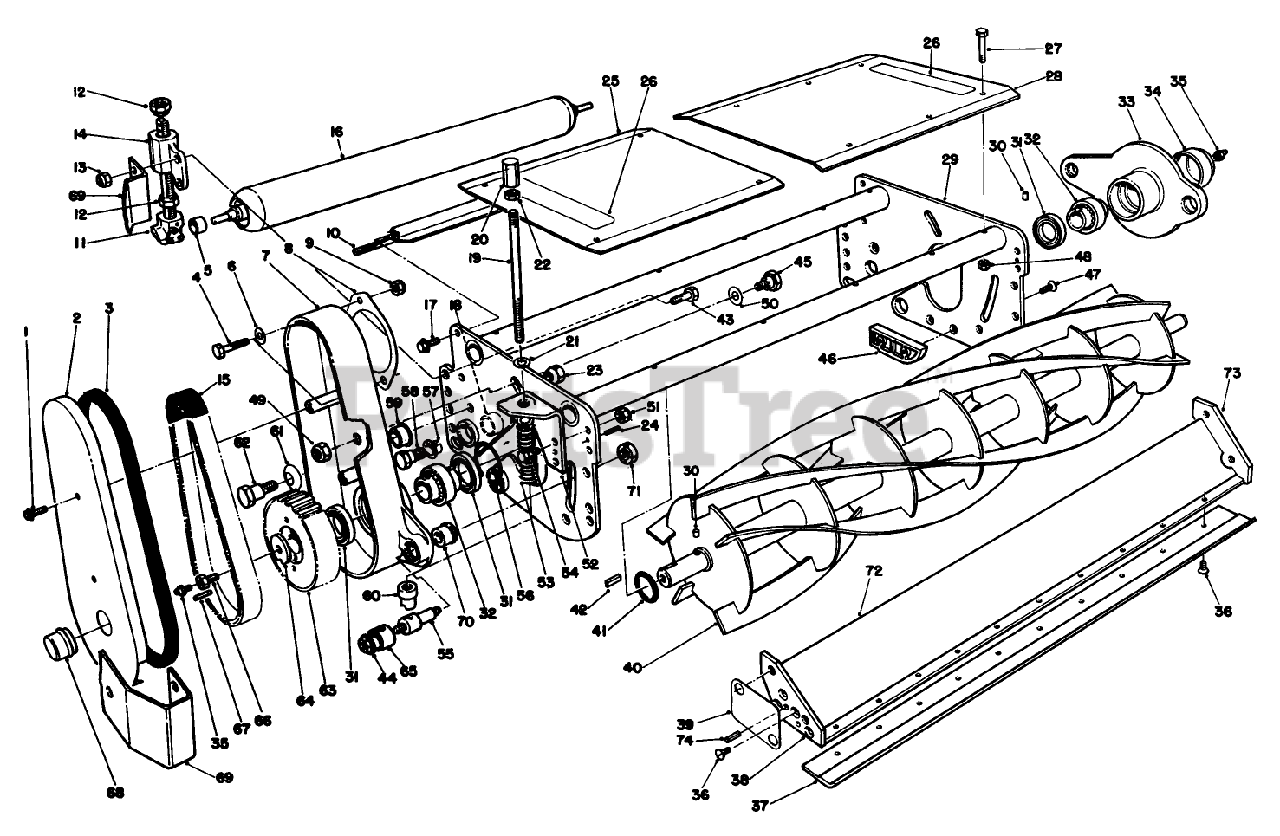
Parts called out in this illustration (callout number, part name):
1	Cover (Incl. Ref. #2-7 & 29)
2	DECAL
3	DECAL
4	WASHER-FLAT
6	DECAL-HOT
7	RING-RETAINING
8	BELT GUIDE
9	WASHER-FLAT
10	NUT-FLANGE
11	BELT GUIDE
12	Deck W.A.
13	PIN-HAIR
14	ROD-SUPPORT
15	DECAL
16	Decal
17	NUT-LOCK, NI
18	DECAL-DANGER
19	WASHER-PLAIN
20	Baffle Deck
21	DECAL-DANGER, THROWN OBJECT
22	NUT-LOCK, SIDE
23	SPRING
24	DECAL-DANGER
25	Deflector Assy. (Incl. Ref. #24)
26	POST-PIVOT
27	SCREW-HH
28	DECAL-DANGER
29	STRIP-MAGNETIC
